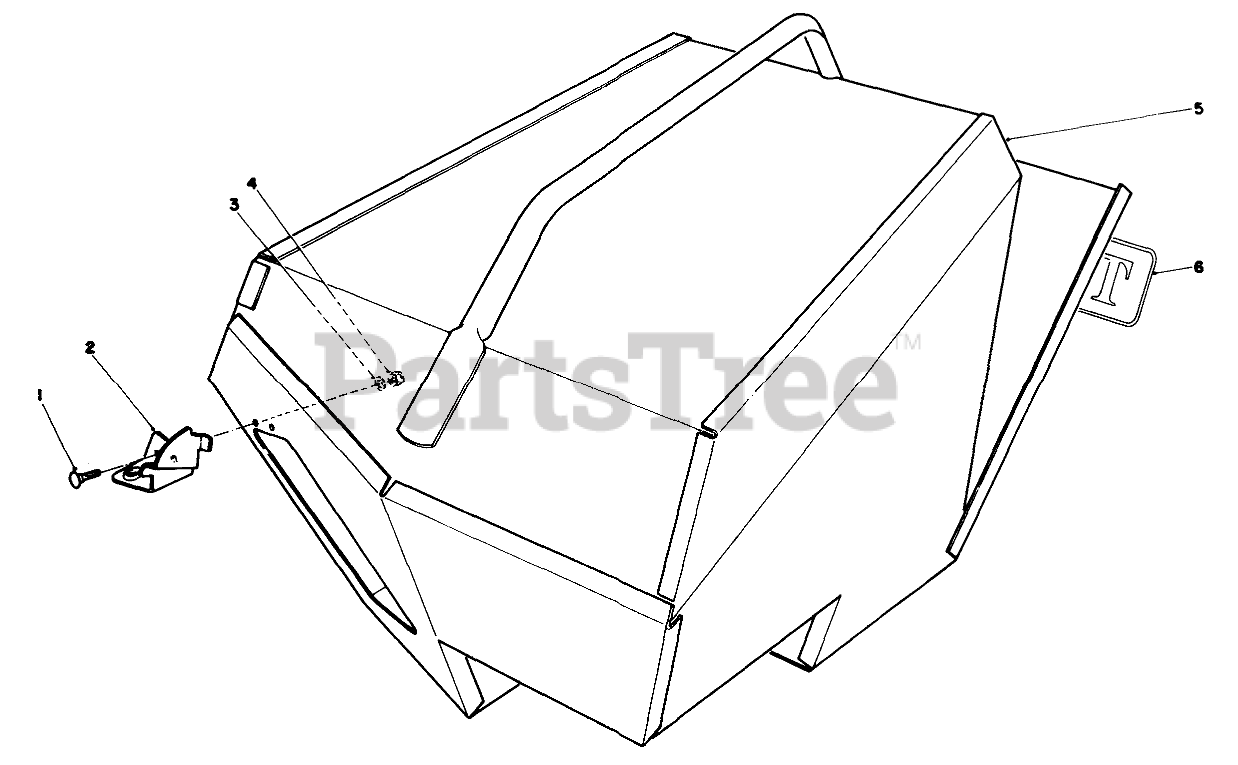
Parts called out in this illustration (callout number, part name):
1	SCREW-CARR
2	Bracket-Latch
3	WASHER-FLAT
4	NUT-LOCK, NI
5	Bag-Steel
6	Decal
